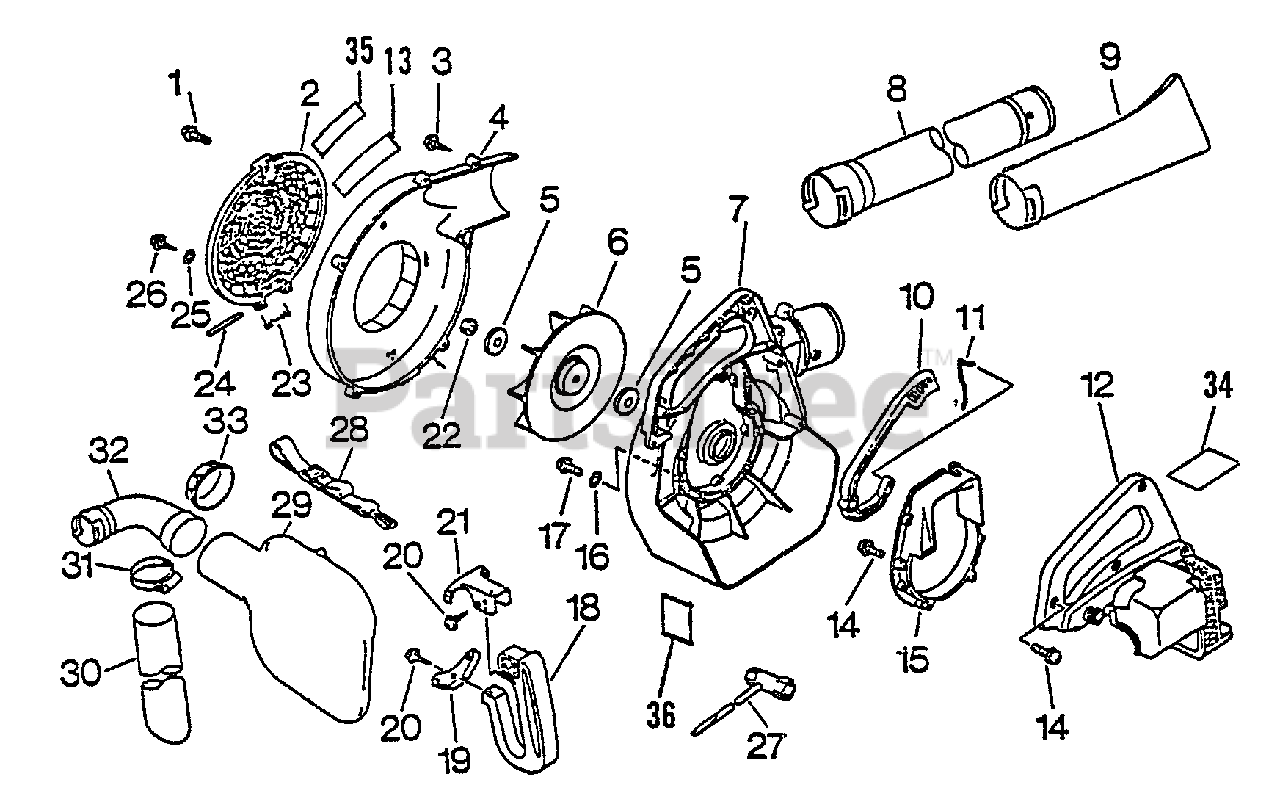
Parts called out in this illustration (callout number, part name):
1	THUMBSCREW
2	GUARD, DEBRIS
3	SCREW - 5X20 -- TAPPING
4	COVER, FAN - LEFT
5	WASHER - 8
6	FAN
7	COVER, FAN - RIGHT
8	TUBE, BLOWER - STRAIGHT
9	NOZZLE - FAN HEAD
10	TRIGGER, THROTTLE
11	ROD, THROTTLE
12	COVER, ENGINE
13	LABEL - MODEL
14	SCREW - 4X18
15	BRACKET, ENGINE
17	SCREW - 4X22
18	HANDLE - REAR
19	BRACKET, HANDLE - LOWER
20	SCREW - 5X14
21	BRACKET, HANDLE - UPPER
26	SCREW - 5X14
27	T-WRENCH - 13X19mm
28	SHOULDER STRAP ASSY
29	BAG, DEBRIS
30	TUBE, VACUUM
32	TUBE, DEBRIS
34	LABEL - HOT SURFACE
35	LABEL - NOISE
36	LABEL - HOT SURFACE
